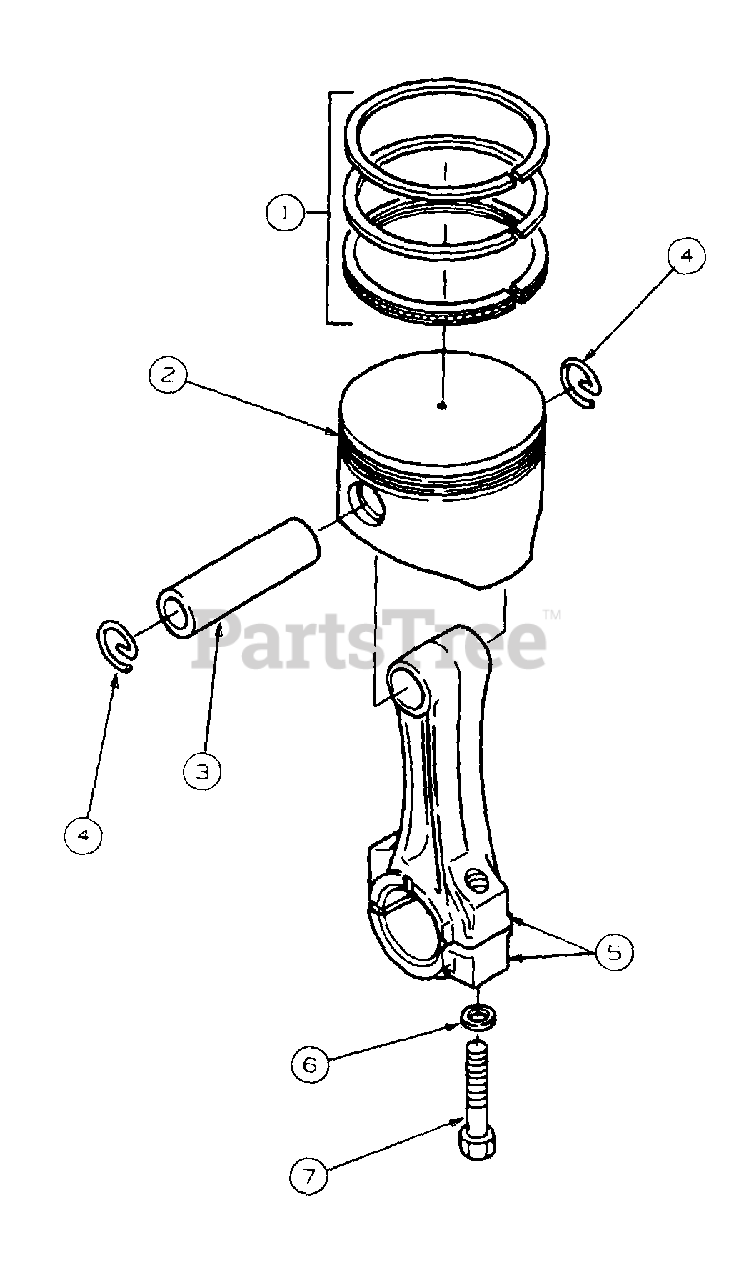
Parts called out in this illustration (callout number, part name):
1	Ring Set, Piston, Std
2	Piston, Std
3	Pin, Piston
4	Ring, Retaining
5	Rod, Connecting, Std
6	Washer, Rod Connecting
7	Bolt, Rod, Connecting
